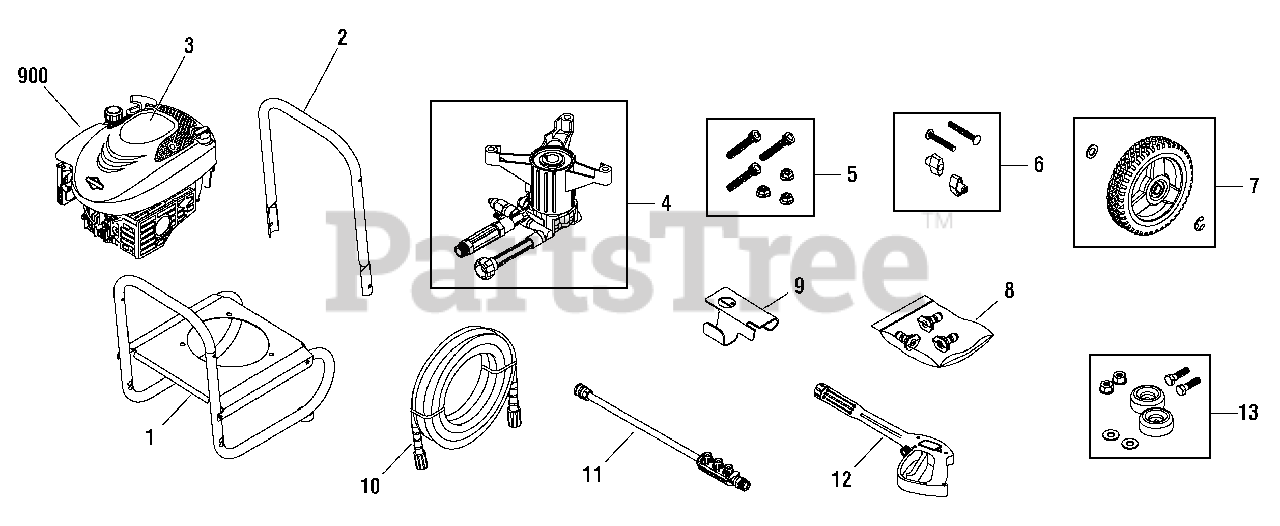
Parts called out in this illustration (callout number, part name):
3	DECAL, Shroud
4	PUMP
5	KIT, Hardware, Pump Mounting
6	KIT, Hardware, Handle
8	KIT, QC Nozzles
10	HOSE
12	GUN
13	KIT, Vibration Mount
900	* ENGINE
